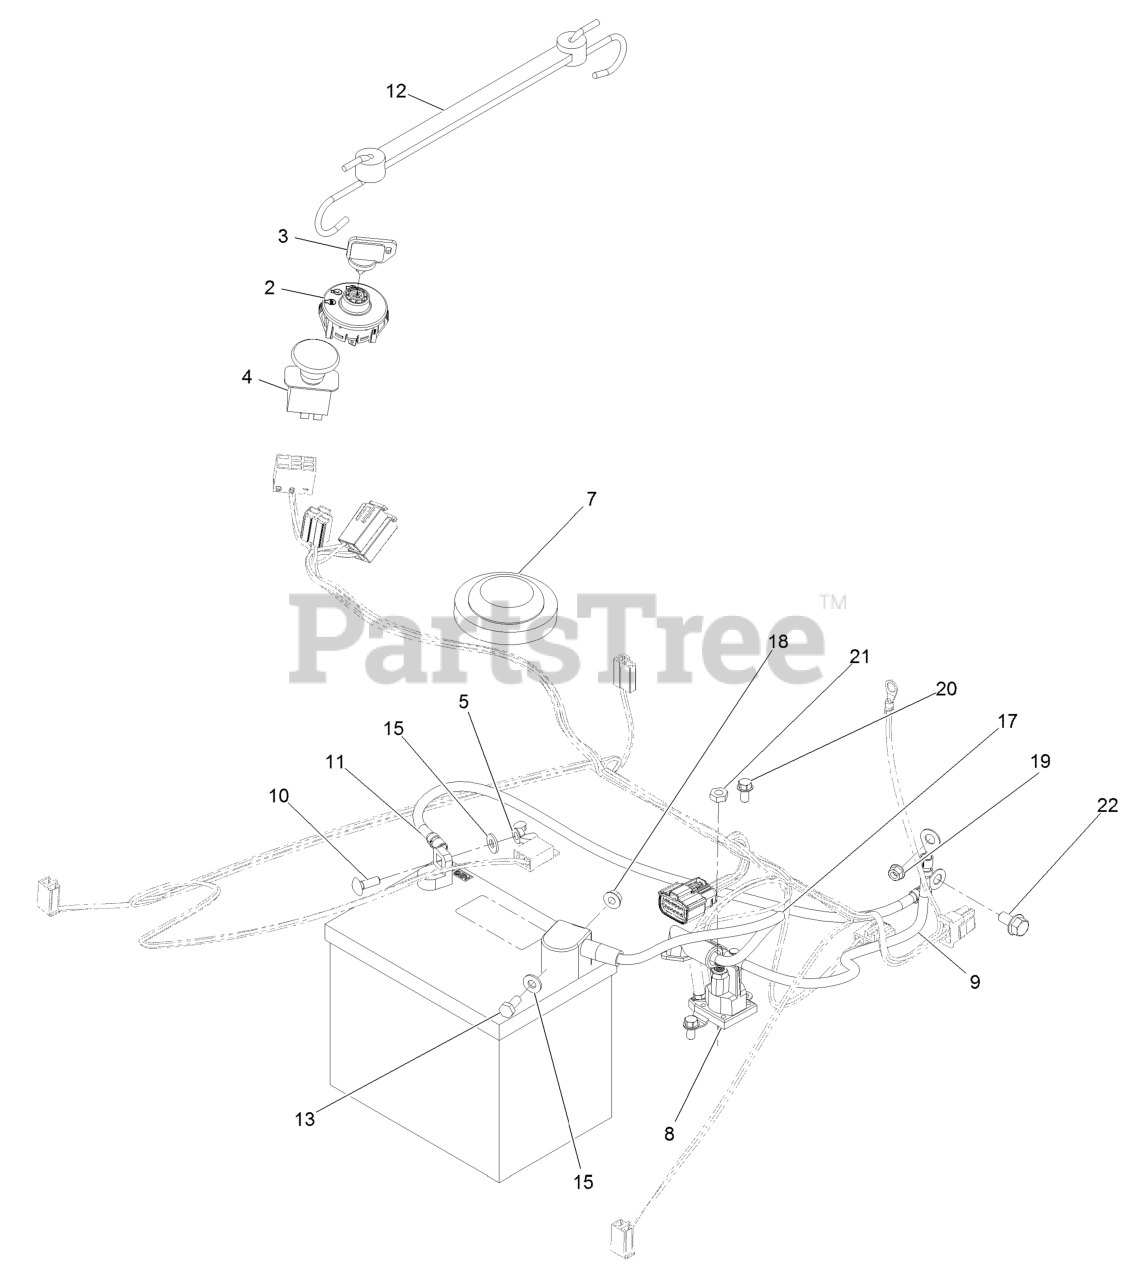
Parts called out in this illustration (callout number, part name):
3	KEY-IGNITION
4	SWITCH-PTO
5	NUT-WING
7	SWITCH-SEAT
8	SOLENOID
9	CABLE-BATTERY, POSITIVE
10	BOLT-CARR
11	CABLE-BATTERY, BLACK
12	HOLDDOWN-BATTERY
13	SCREW-HH
15	WASHER-FLAT
17	CABLE-BATTERY, RED
20	SCREW-HWH
21	NUT-JAM
22	SCREW-HHF
